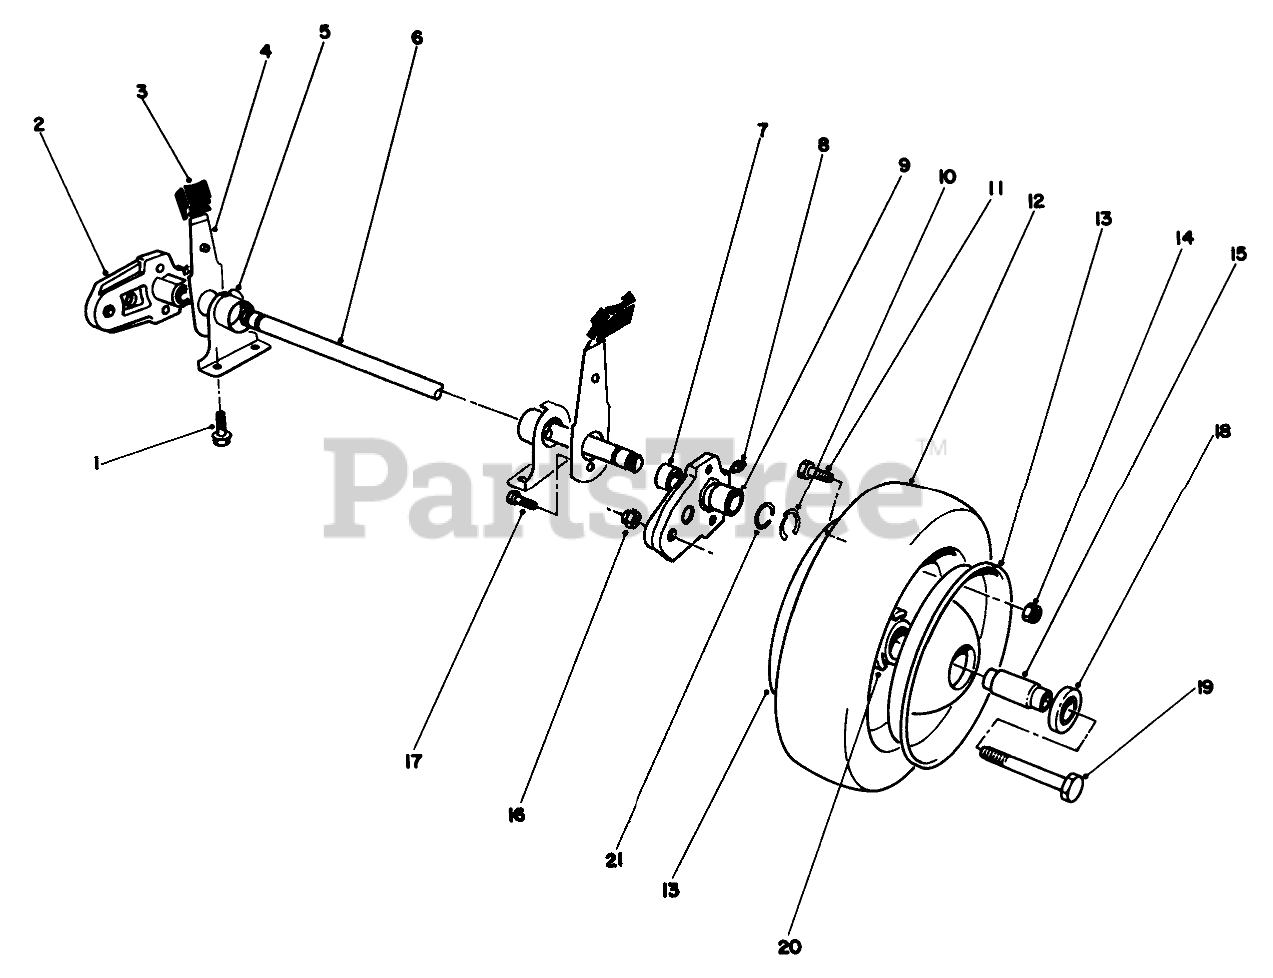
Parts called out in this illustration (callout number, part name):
1	SCREW-HWHTF
2	Pivot Arm Assembly (Incl. Ref. #7-9)
3	KNOB-ARM
4	SPRING ARM ASM
5	CAP-END
6	SHAFT - AXLE
7	BUSHING
8	FITTING-GREASE
9	BEARING-ROLLER
10	RING-CLIP, LOCKING
11	SCREW-HH
13	Wheel-Half
14	NUT-LOCK, NI
15	SPACER-BEARING
16	NUT-LOCK, NI
17	SCREW-HSH, THREAD FORMING
18	BEARING-WHEEL
19	SCREW-HH
20	HUB-BEARING
21	RING-RETAINING
